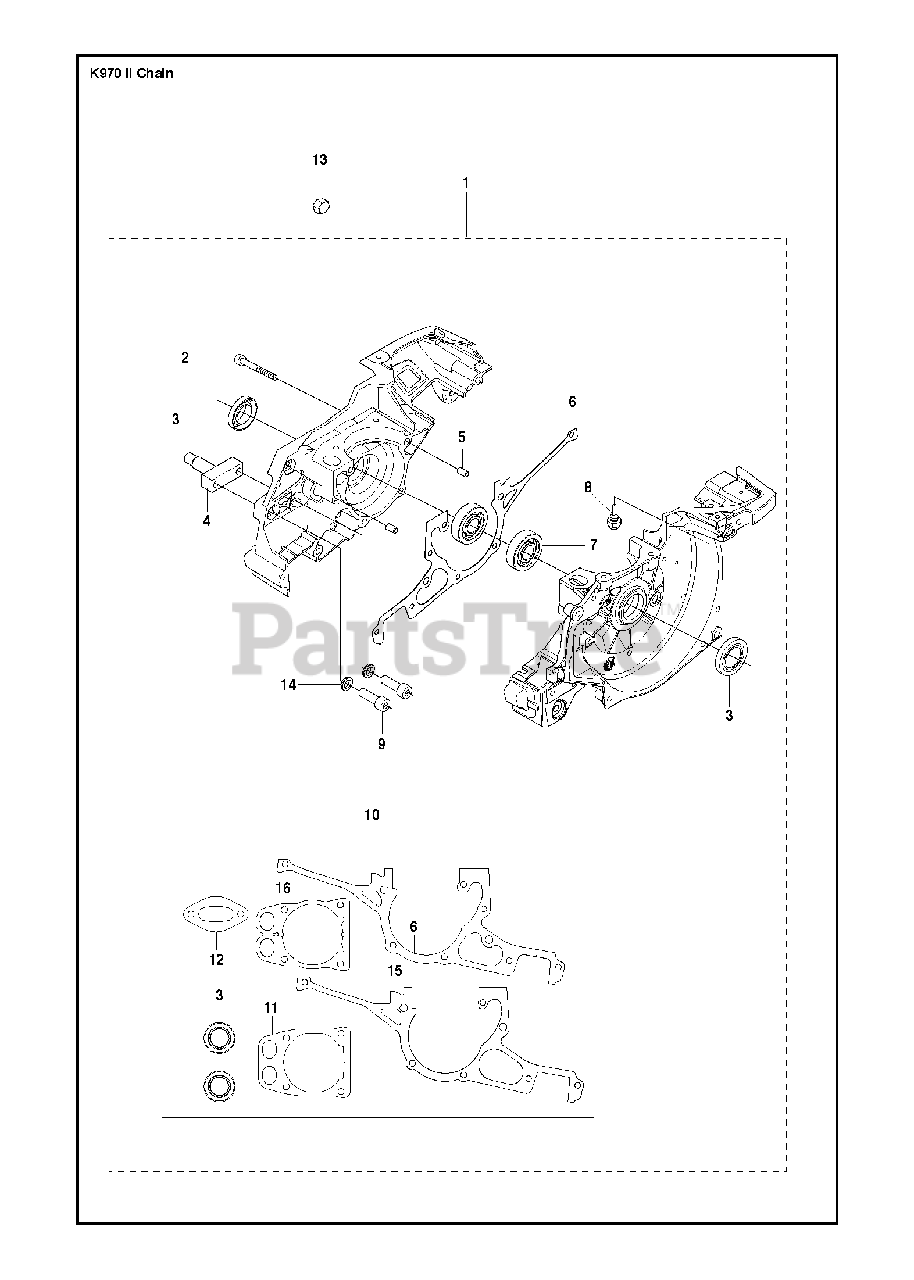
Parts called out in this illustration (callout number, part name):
1	CRANKCASE ASSYIncl. 2 - 10, 14
2	SCREW ITXSCM
3	SEALING RING
5	GUIDE BUSHING
7	BALL BEARING
8	RUBBER BUSHING
10	GASKET KITIncl. 3 , 6, 11-12, 15-16
12	GASKET
